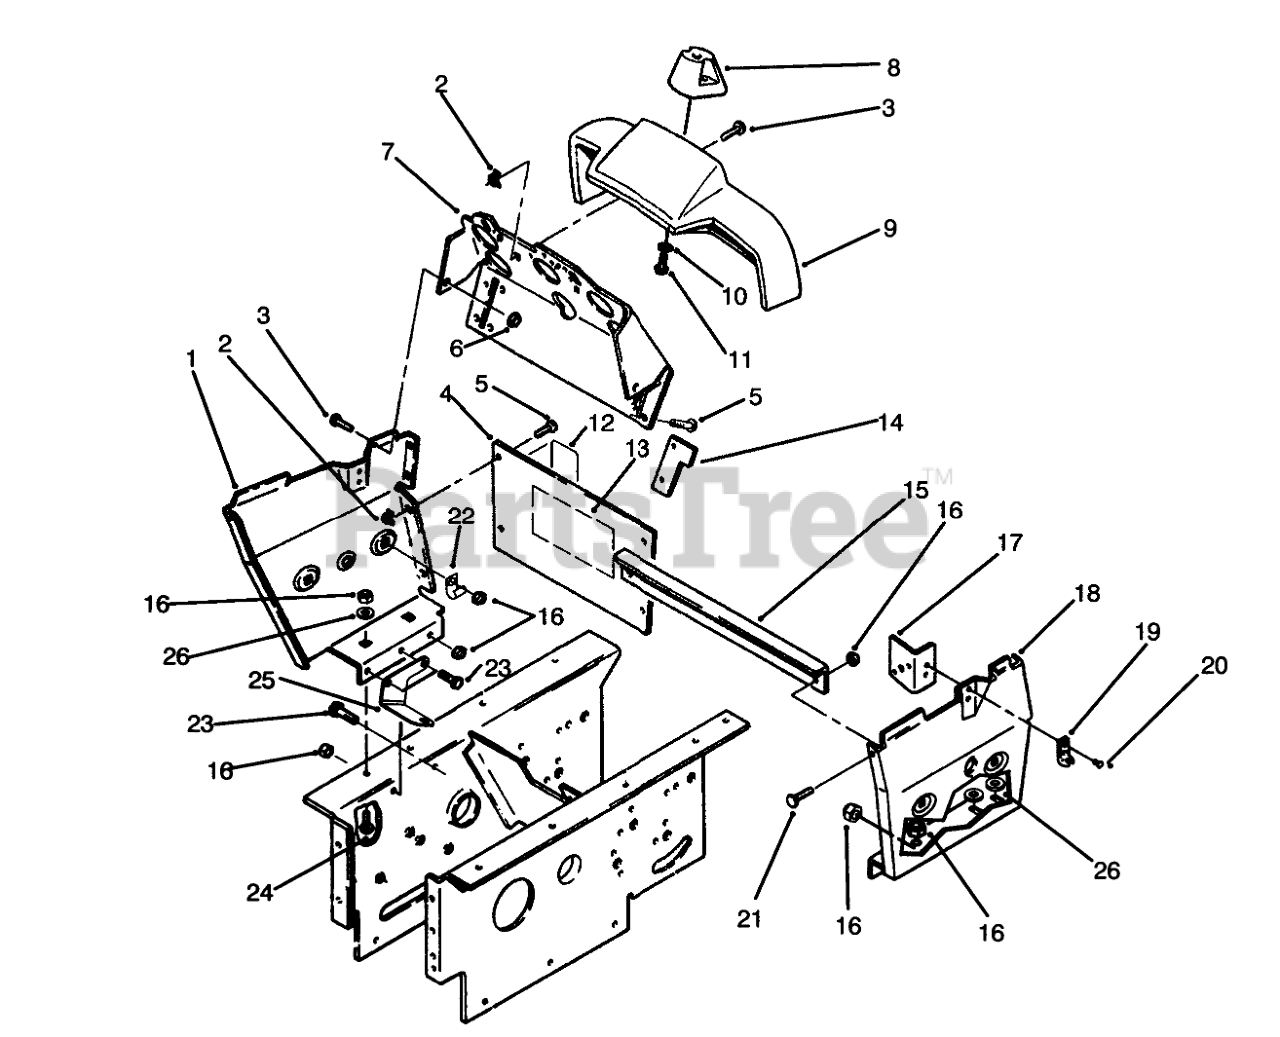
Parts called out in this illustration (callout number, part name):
1	Panel-RH
2	NUT-RETAINED
3	Screw
4	Plate-Hoodstand, Rear (Incl. Ref. #13)
5	Screw
6	NUT-HF
7	ASM-Panel
8	COVER-STEERING SHAFT
9	COVER-CONSOLE 5 GAGE
10	SWIVEL JACK
11	SCREW-#6 PLASTITE
12	DECAL PTO CLUTCH
13	DECAL - DANGER
14	STOP-CHOKE
15	STIFFENER-PANEL B
16	NUT-LOCK, NI
17	BRACKET-SWITCH SU
18	Panel-LH
19	KEEPER-LATCH
20	RIVET-POP
21	SCREW-HH
22	CLIP
23	SCREW-HH
24	CARRIAGE BOLT -4
25	Bracket-Control
26	WASHER-PLAIN
